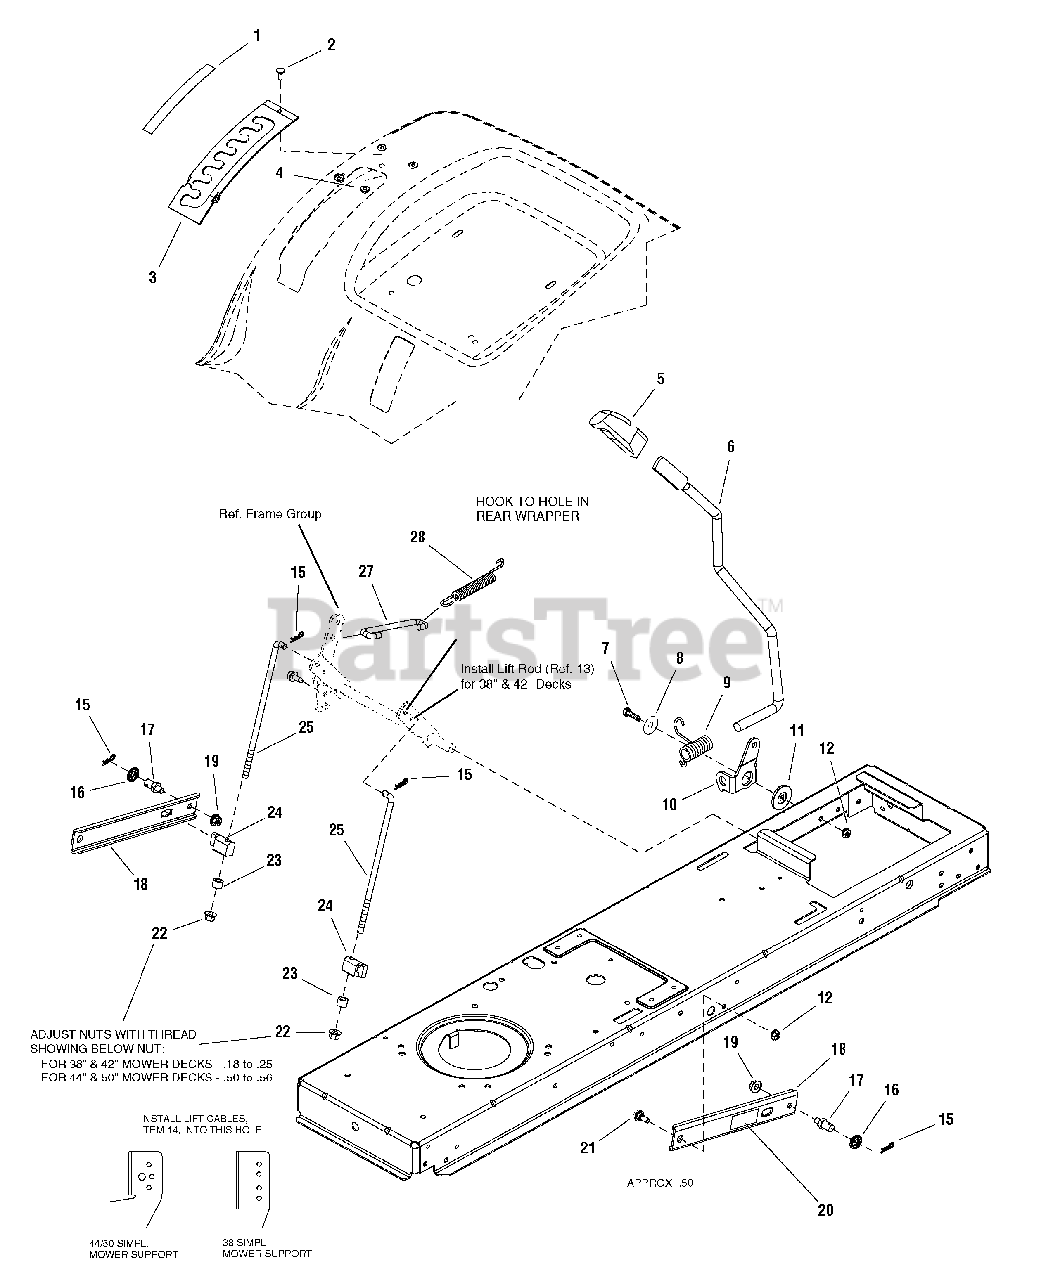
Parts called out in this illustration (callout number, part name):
1	DECAL, Height Of Cut
2	CARRIAGE BOLT, 1/4-20 x 5/8 G5
3	QUADRANT, Lift Height 12GA
4	NUT, Hex Flange Whiz, 1/4-20
5	GRIP
6	ROD, Lift Handle E-Coat, 17.7 LG
7	CAPSCREW, Hex Head, 5/16-18 x 1
8	WASHER, Plain, 21/64 x 1-1/4
9	SPRING, Torsion, 2.12 LG Black
10	CLEVIS, Lift 7GA
11	SPACER, Pivot 0.330ID 1.76OD .37TH Powdered Metal
12	NUT, Hex, Flange Whizlock, 5/16-18
15	CLIP, Spring
16	WASHER, 1/2
17	PIN, Threaded Shoulder
18	ARM, Lift Rear 10GA
19	NUT, Hex, Flange, Whizlock, 3/8-16
20	DECAL, CAUTION! Pinch Point
21	BOLT, Shoulder
22	NUT, Hex Flange, 3/8-16 ESNA
23	SPACER
24	TRUNNION, Powdered Metal
25	ROD, Lower Lift, 10.00 LG
27	ROD, Lift, 5.43 LG
28	SPRING, Extension 5.10 LG Black
